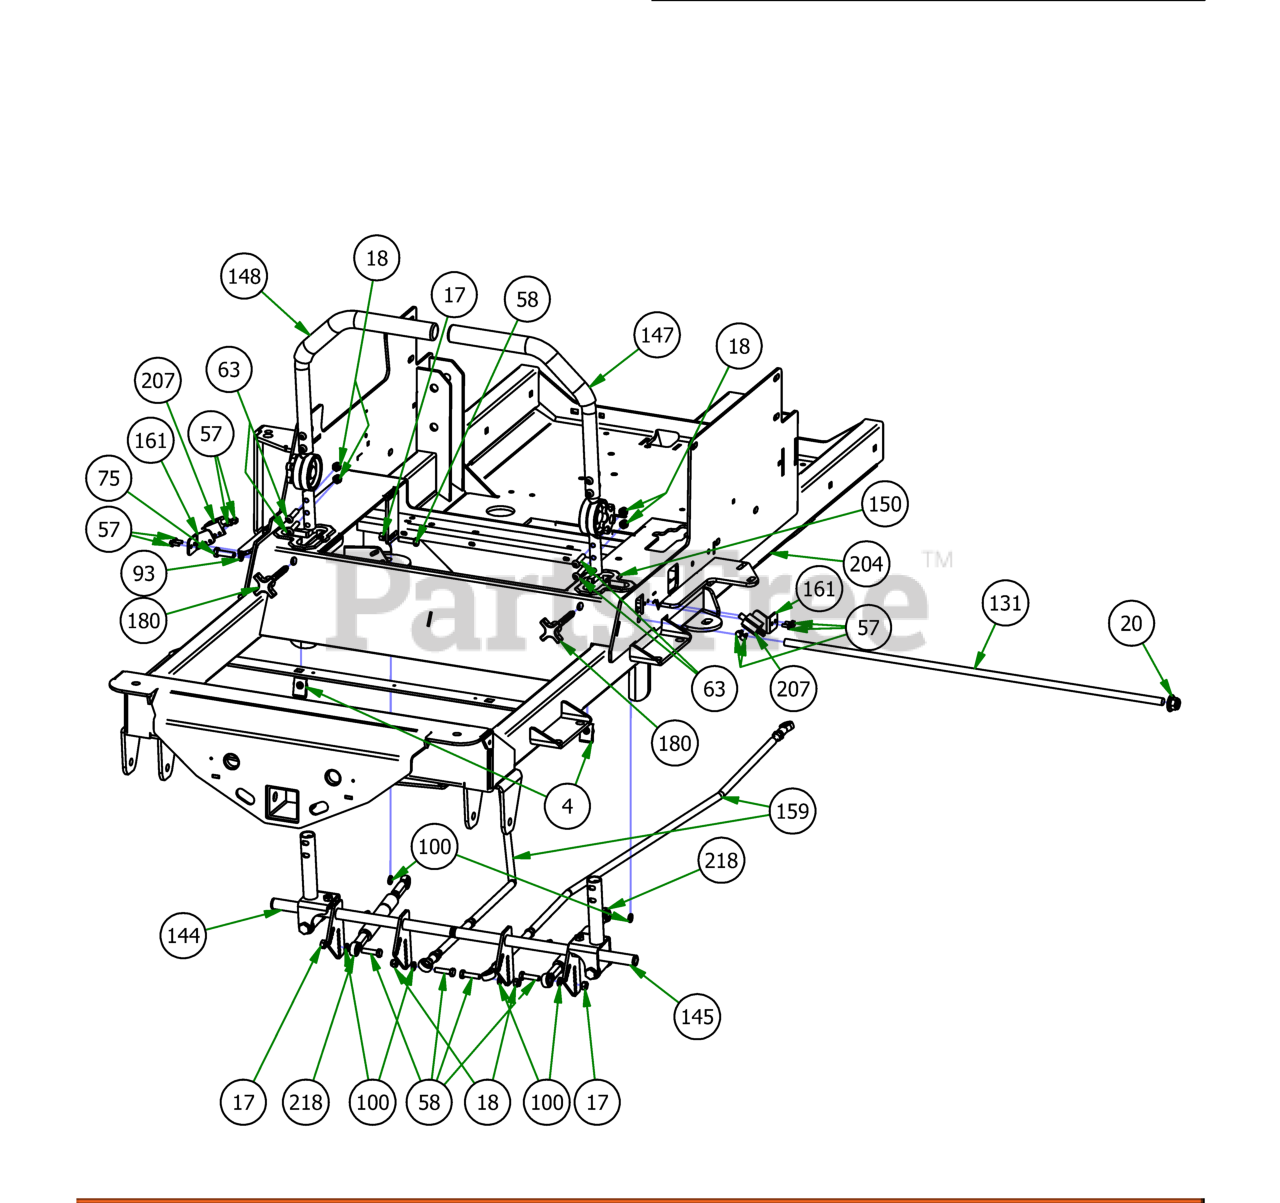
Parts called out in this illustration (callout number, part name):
4	Extruded Nut 3/8"-16 3/4" Hole Center With Patch
18	5/16-18 NYLON INSERT LOCKNUT ZINC ORANGE NYLON
20	1/2-13 NYLON INSERT FLANGE LOCKNUT ZINC
23	5/16" Flange Nut
57	12-24x 1/2 HWH Bolt
58	5/16 x 1 1/4 Hex Bolt
63	5/16-18 UNC X 1-3/8" BHCS, TORX DRIVE, GR 5
75	3/8" x 1 1/4" Hex Bolt
93	3/8" Lock Washer
100	5/16" Lock Washer
131	2019 Steering Actuator Rod
144	2019 R Series RH Arm Rod Assembly
145	2019 R Series LH Arm Rod Assembly
147	2019 Left Hand ADJ. Steering Arm Kit
148	2019 Right Hand ADJ. Steering Arm Kit
150	Snap-In Bushing-2019
159	2019 Renegade Push Rod Assembly
161	2019 Arm Switch Bracket
180	Speed Limiting Knob 3/8-16X 3"
204	2019 Renegade Gas Frame - Powdercoated
207	Safety Switch
218	2019 SROID Damper With Spherical Rod Ends
